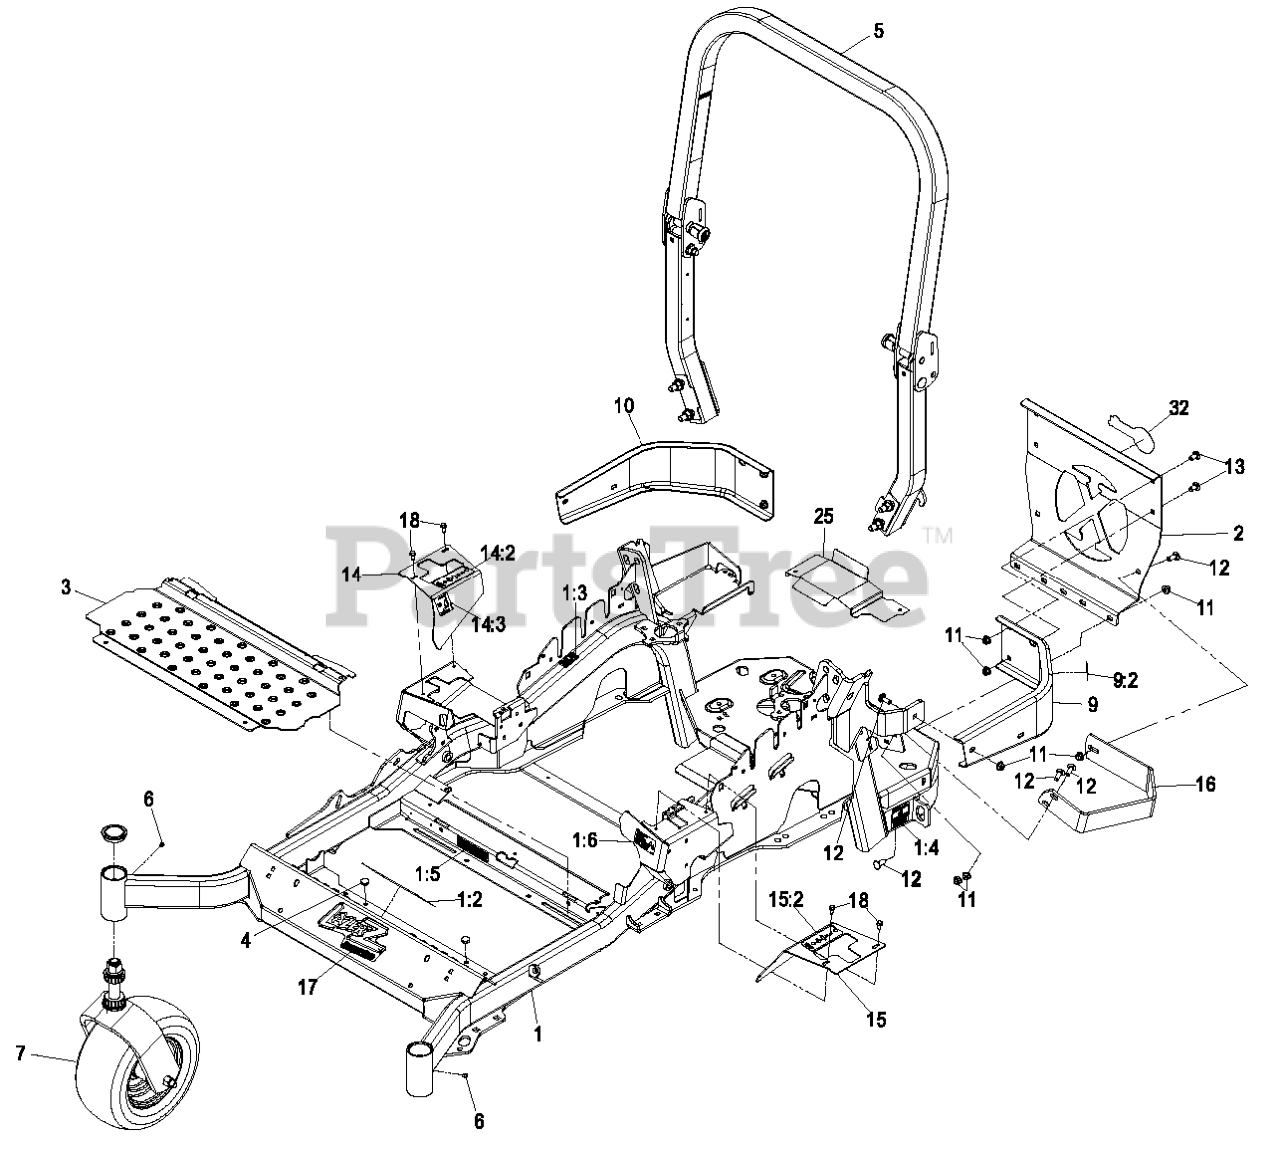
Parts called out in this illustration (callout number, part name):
1	MAIN FRAME ASM
1:2	DECAL-WARNING
1:3	DECAL-CAUTION
1:4	DECAL-BELT DRIVE
1:5	DECAL-ARRESTER, SPARK
1:6	DECAL-FUEL FILL
2	PLATE,REAR GUARD
5	ROPS ASM
7	Asm, Caster Wheel
9	LH BUMPER ASM
9:2	DECAL-CAUTION
10	BUMPER-RH
11	NUT-HF, NI
12	SCREW-CARR
13	SCREW-CARR
14:2	DECAL-MOTION CONTROL
15	LH MOTION CONTROL COVER ASM
15:2	DECAL-MOTION CONTROL
17	DECAL,LAZER AS LOGO
18	SCREW-HWH
25	GUARD-BELT
